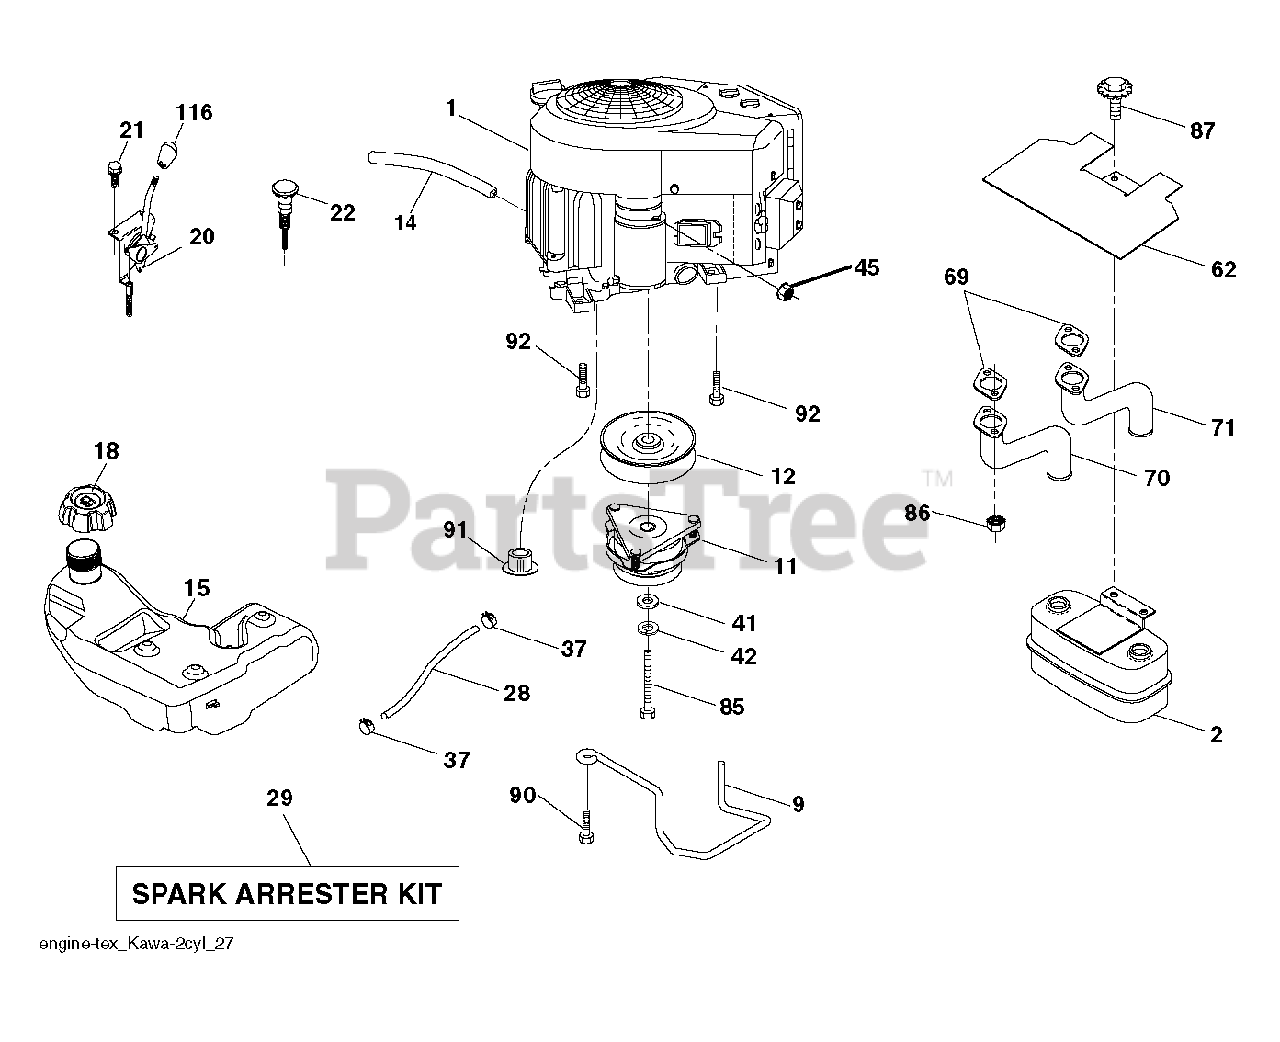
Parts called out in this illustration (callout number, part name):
2	MUFFLER.ASM.TWN.EXTNDED.DFLCTR
9	KEEPER BELT ENGINE
11	RB.CLUTCH.OGURA.4.4.PD
12	PULLEY.ENGINE.TUFFTORQ
14	TUBE, DRAIN OIL ASM.
15	TANK.ASSY.3.GAL.EPA
18	CAP.ASM.FL.RITCH.3"E10.SYM.498
20	CONTROL.THROTTLE.PRO.
21	SCREW.#10 X 0.750.BOS
22	CONTROL, CHOKE
28	LINE.FUEL.64"REAR.EMIS
29	KIT.SPARK ARRESTOR 794945 B&S
37	HOSE CLAMP
42	LOCKWASHER
45	NUT
62	SHIELD.HEAT.MUFFLER
70	TUBE.EXHAUST.LH.FR961/FR730
71	TUBE.EXHAUST.RH.FR961/FR730
85	BOLT HEX 7/16-20X4-1/4"
86	NUT.HEX.FLANGE.TOPLOCK
87	BOLT, 5/16-18 X 1 3/4
90	SCREW 3/8-16X1
91	BUSHING.1.375OD
92	SCREW 3/8-16X1
116	KNOB - SHIFT
